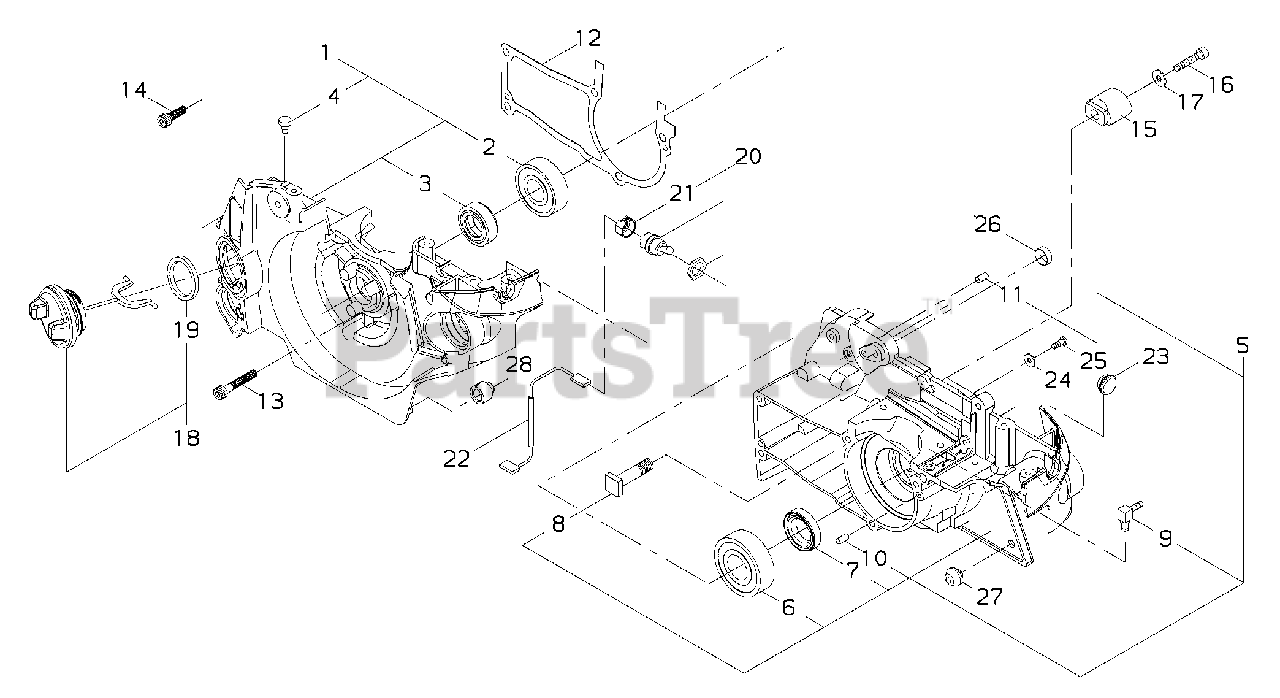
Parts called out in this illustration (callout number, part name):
1	CRANKCASE ASSY, M
2	BEARING, BALL 6201C3
3	SEAL, OIL 12
4	VENT ASSY
5	CRANKCASE ASSY, C
6	BEARING, BALL 6202C3
7	SEAL, OIL
8	BOLT, STUD 8
9	CONNECTOR, PIPE
10	PIN, LOCATING Ø4×8
11	PIN, LOCATING Ø4×11
12	GASKET, CRANKCASE
13	BOLT M5×35
14	BOLT M5×18
15	CHAIN CATCHER
16	BOLT M5×25
17	WASHER, FLAT 5.5×10×0.8
18	CAP ASSY, OIL
19	GASKET, CAP
20	SWITCH ASSY, ON-OFF
21	CAP, SWITCH
22	LEAD - IGNITION
23	PLUG
24	WASHER 4 MM
25	SCREW M4×7
26	COLLAR 8
27	CUSHION C
28	CUSHION M
